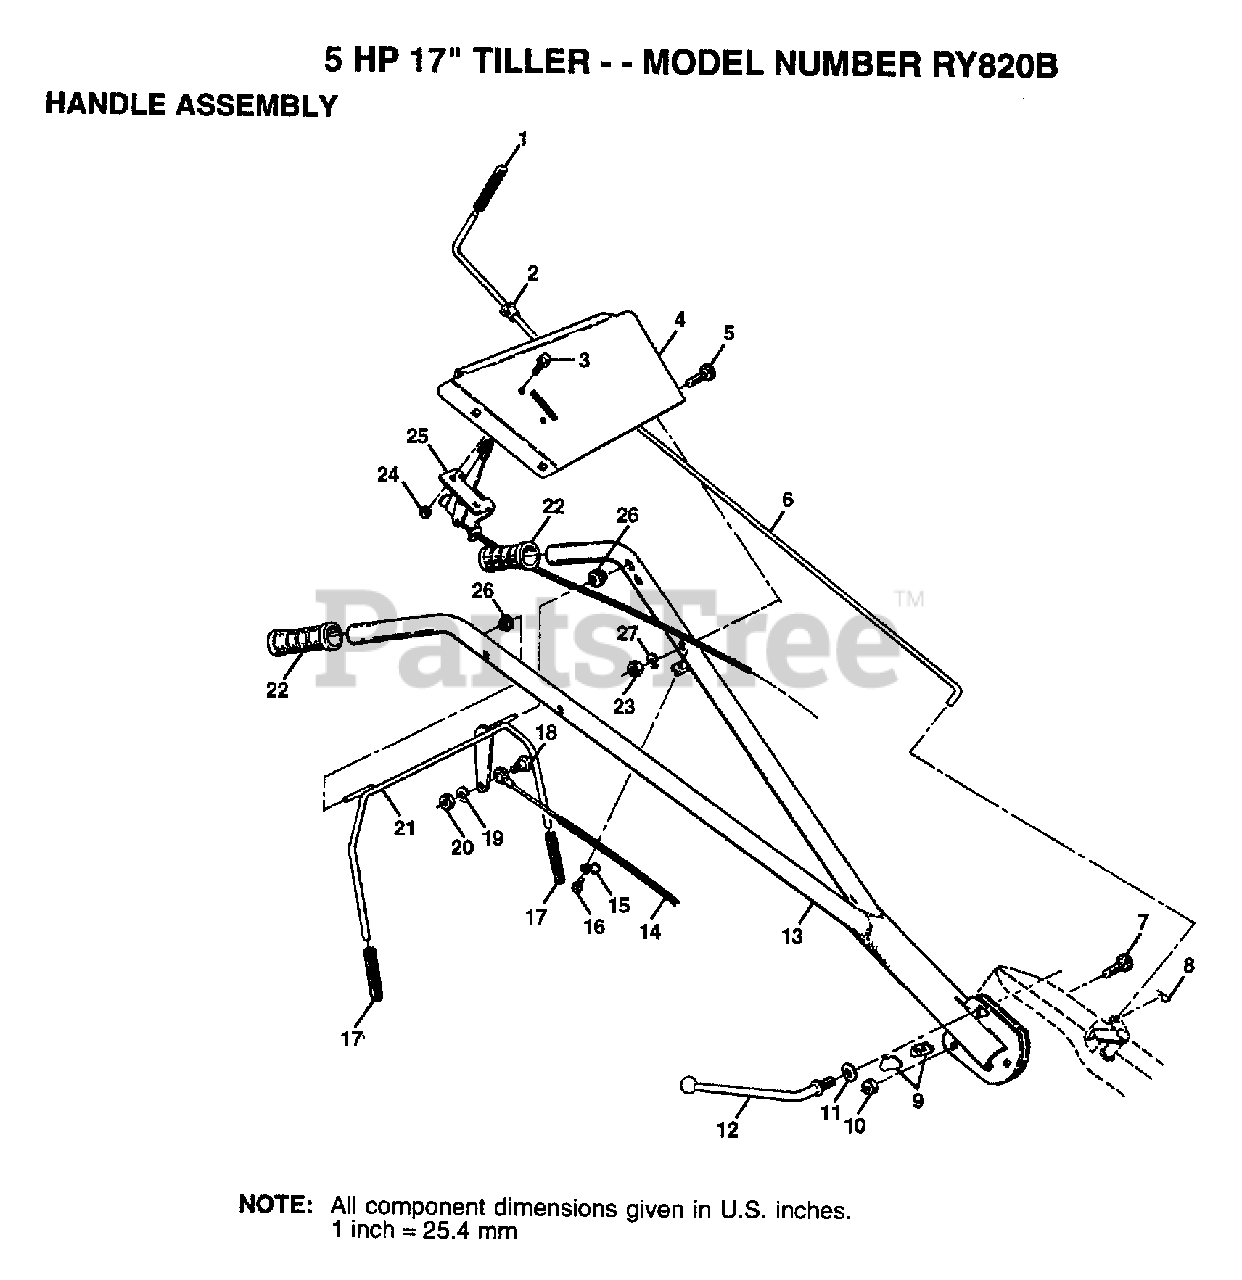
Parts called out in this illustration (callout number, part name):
1	GRIP TI
2	BUSHING
3	SCREW
4	HANDLE BRACKET
5	BOLT CARRIAGE CRT
6	ROD SHIFT CRT
7	BOLT D
8	RETAINER M
9	LOCK CRT
10	LOCKNUT
11	WASHER CRT
12	LEVER LOCK CRT
14	CABLE.CLUTCH.CRT
15	CONDIUT CLIP T
17	GRIP BAR CRT
18	SHOULDER BOLT ST
19	LOCKWASHER
21	HANDLE BAR CRT
22	GRIP HDLE NUBBED
23	NUT
25	"CONT,THROTTLE"
27	LOCKWASHER
